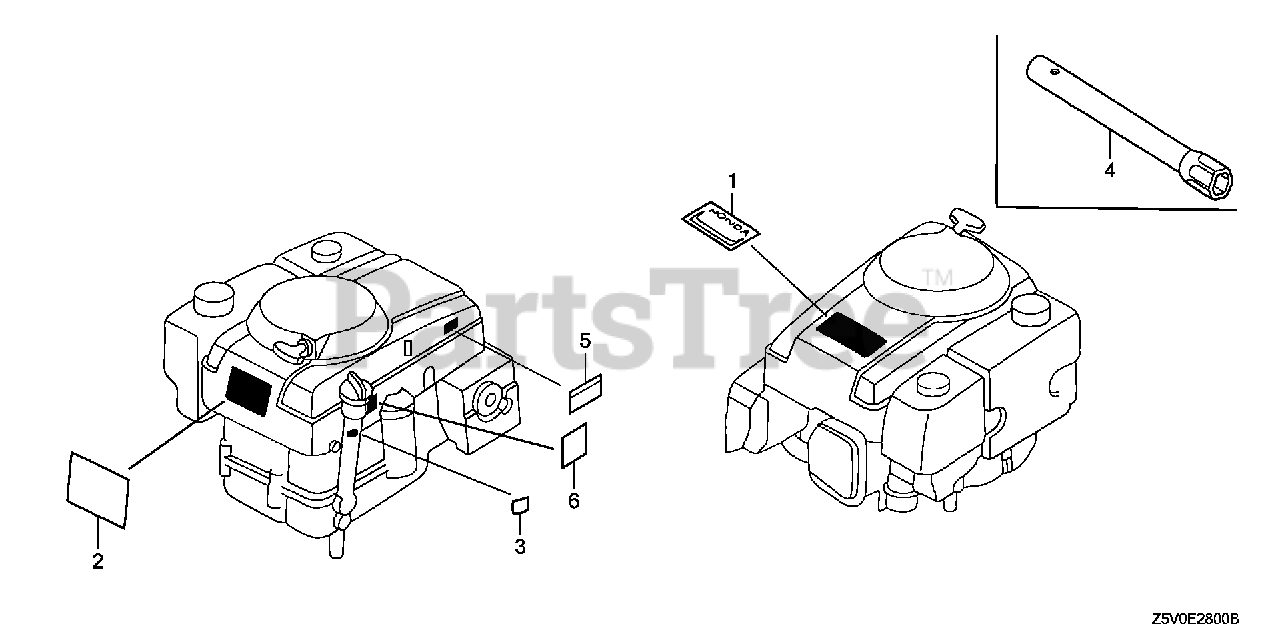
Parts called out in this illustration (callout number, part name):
1	EMBLEM, TOP COVER (GXV390)
2	MARK, OPERATOR CAUTION (PICTOGRAPH)
3	MARK, TYPE (DAE4)
4	WRENCH, BOX (P21)
